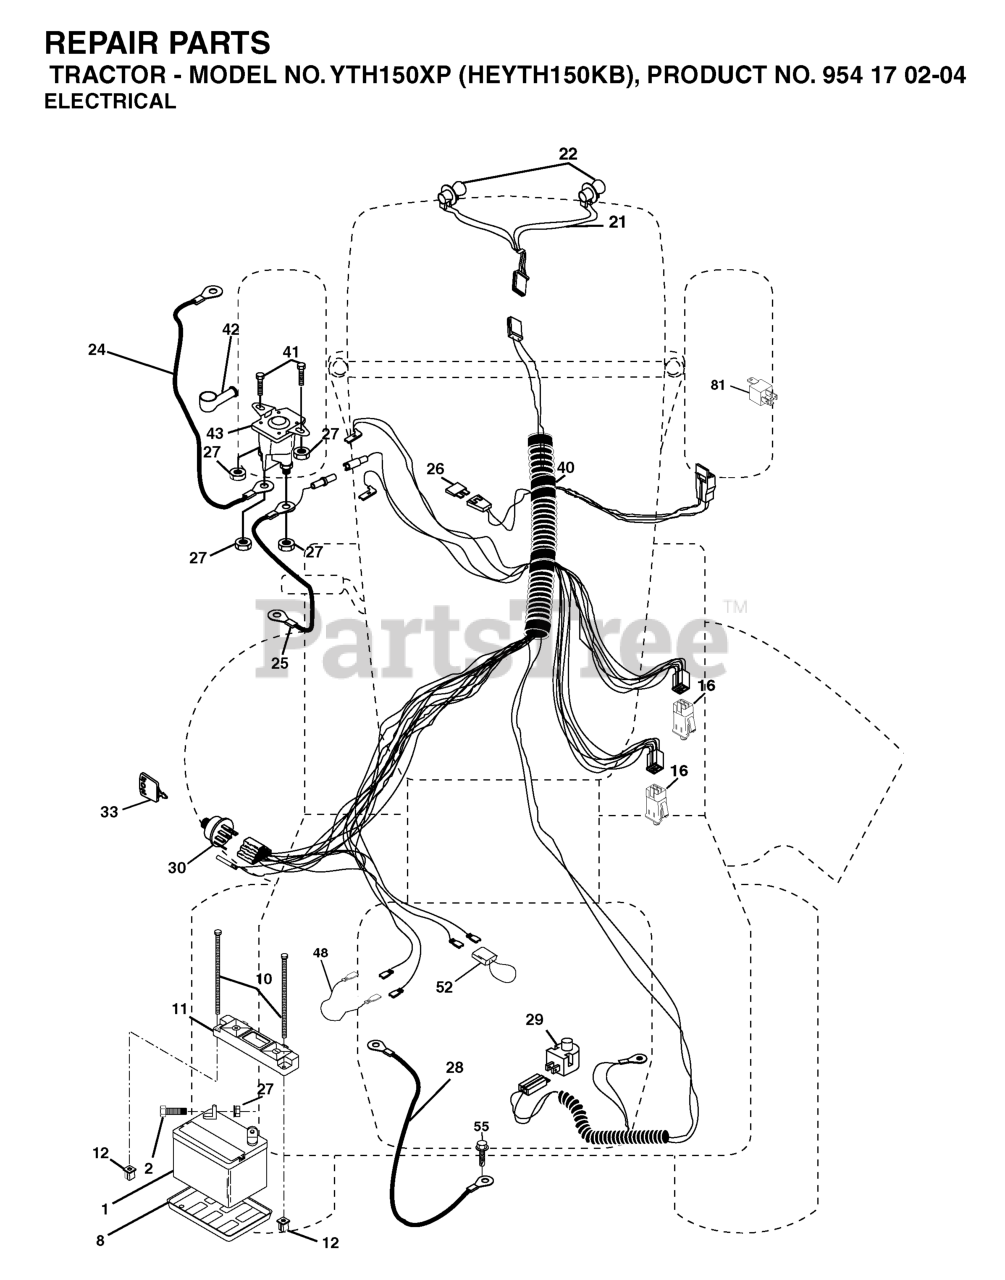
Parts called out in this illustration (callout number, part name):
1	BATTERY 12V .35 AMP
2	BOLT.HEX.1/4.X.3/4.DICHROMATE
8	BATTERY TRAY T
10	BOLT 1/4-20 X 7.5
11	BATTERY HOLDDOWN FRONT MOUNT
12	NUT, PUSH NYLON 1/4" BATTERY
16	SWITCH INTERLOOK PUSH-IN
21	HARNESS.W/LIGHT SOCKET
24	BATTERY CABLE GT
25	CABLE BATTERY 6 GA 22" W/16W
26	FUSE 20AMP
27	NUT
28	CABLE GROUND 6 GA 21" 90T BLK
29	RP.SWITCH.PLUNGER.NC.GRAY
30	IGNITION SWITCH
33	KEY MLD GEN DELTA
40	HARNESS.IGNITION
41	BOLT
42	TERMINAL COVER
43	SOLENOID
48	ADAPTER.AMMETER
52	WIRE PROTECTION LOOP
55	Screw 5/16-18 x 1/2 Hex, Self Tapping 5/16-18 x 1/2
81	RELAY.ASSY.T
